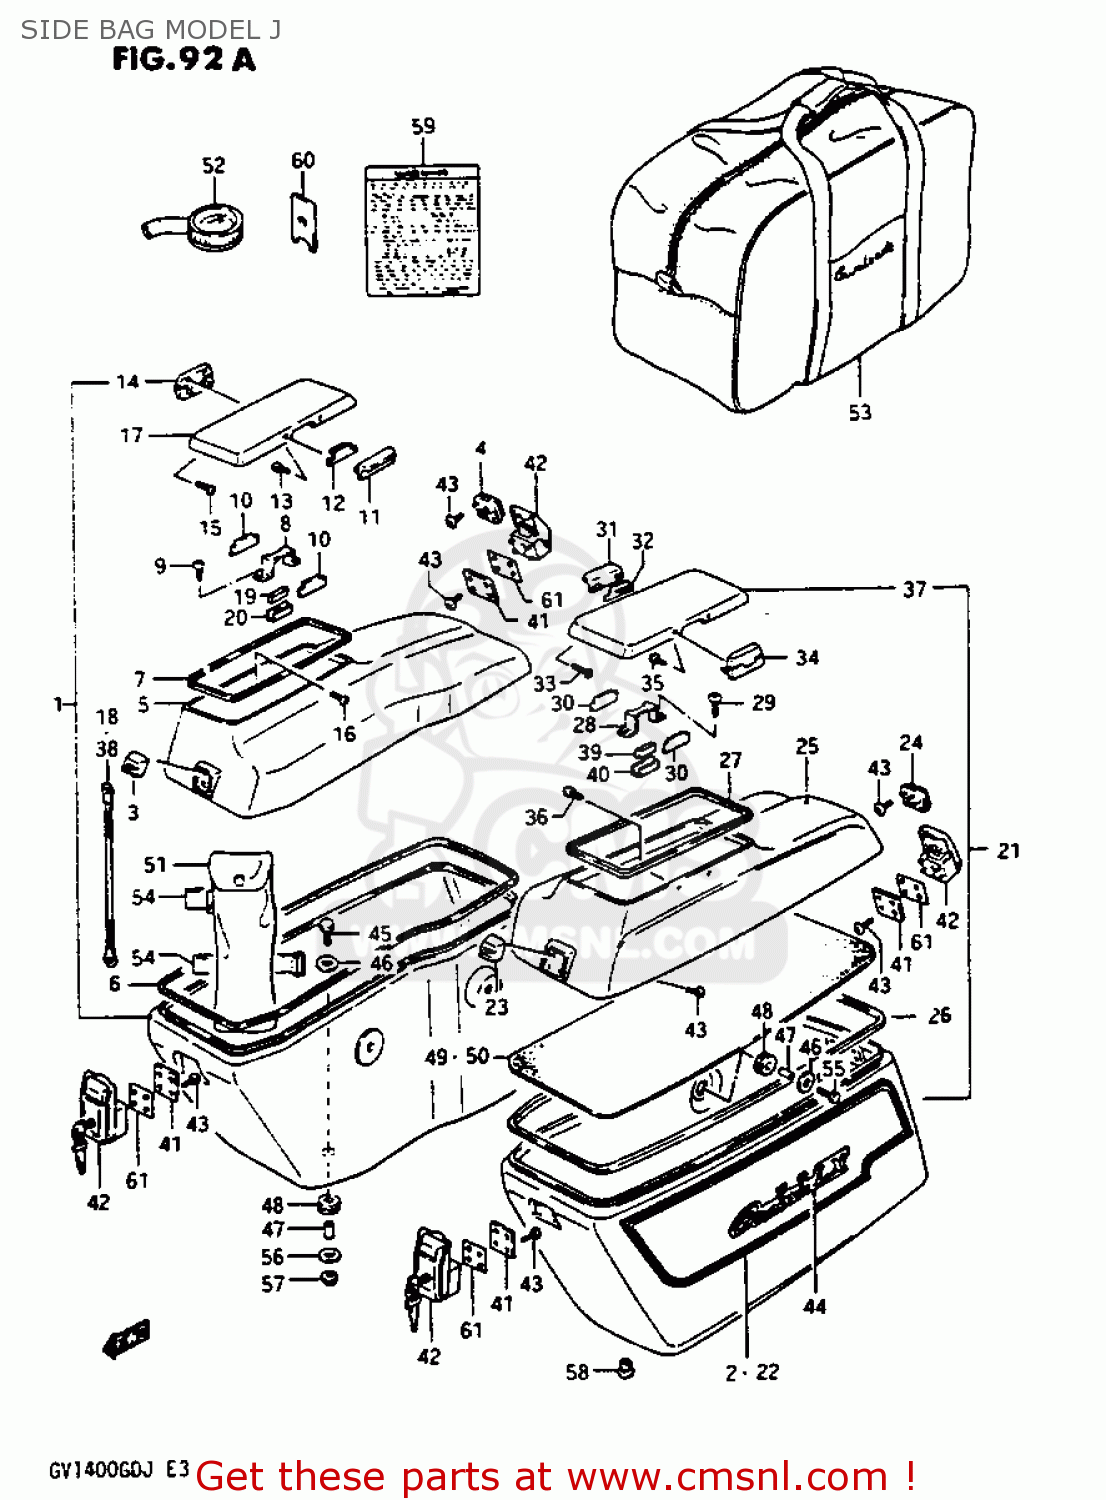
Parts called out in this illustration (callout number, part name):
1	BAG ASSEMBLY,SIDE,RIGHT
2	TAPE SET,SIDE BAG,RIGHT
3	PLATE,TRUNK LID LOCK
4	PLATE,SIDE BAG LID LOCK
5	LID,SIDE BAG,RIGHT
6	SEAL,SIDE BAG
7	SEAL,SIDE BAG
8	HOLDER,LID LOCK MAGNET
9	SCREW
10	PLATE,LID LOCK
11	LEVER,SIDE POCKET OPEN
12	PLATE,LID LOCK NO.1
13	SCREW
14	HINGE,LID SIDE BAG POCKET
15	SCREW
16	SCREW
17	LID,SIDE BAG POCKET
18	BAND,SIDE BAG LID
19	MAGNET
20	BOX, HOLDER
21	SIDE BAG ASSEMBLY,LEFT
22	TAPE SET
23	PLATE,TRUNK LID LOCK
24	PLATE,SIDE BAG LID LOCK
25	LID,SIDE BAG,LEFT
26	SEAL,SIDE BAG
27	SEAL,SIDE BAG
28	HOLDER,LID LOCK MAGNET
29	SCREW
30	PLATE,LID LOCK
31	LEVER,SIDE POCKET OPEN
32	PLATE,LID LOCK NO.1
33	SCREW
34	HINGE,LID SIDE BAG POCKET
35	SCREW
36	SCREW
37	LID,SIDE BAG POCKET
38	BAND,SIDE BAG LID
39	MAGNET
40	BOX, HOLDER
41	SET PLATE,LOCK SIDE BA
42	LOCK SET,SIDE BAG
43	SCREW
44	EMBLEM,SIDE BAG,RIGHT
45	BOLT
46	WASHER (6.5X29X1.6)
47	SPACER(6.3X9.3X16.5)
48	CUSHION
49	SEAT, BOTTOM RH
50	SEAT, BOTTOM LH
51	SCREW
52	EMBLEM,SIDE BAG,RIGHT
53	EMBLEM
54	BAND
55	BOLT(6X30)
56	WASHER (6.5X18X2)
57	NUT
58	CAP(OD:12)
59	SEAT, BOTTOM LH
60	SPANNER
61	PACKING SEAT
62	LUGGAGE BAG,SIDE BAG
63	BAND
64	BOLT(6X30)
65	WASHER (6.5X18X2)
66	NUT
67	CAP(OD:12)
68	LABEL (WARNING TRAVEL T
69	SPANNER
70	PACKING SEAT
